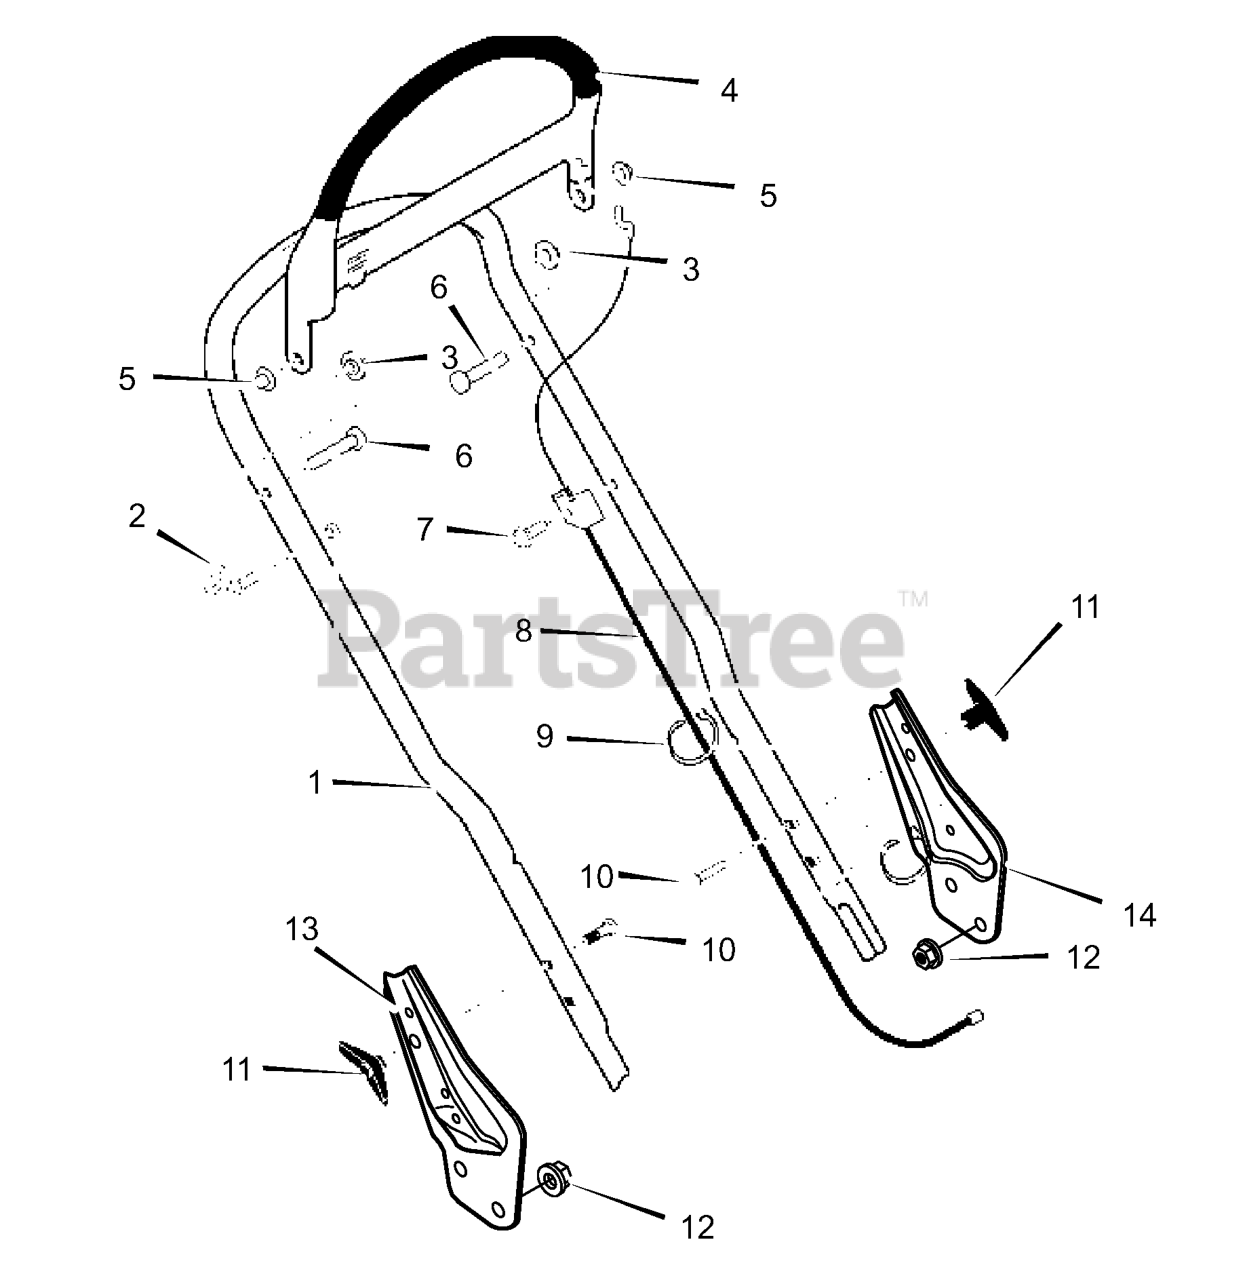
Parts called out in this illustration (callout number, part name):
1	Handle, Upper
2	Guide, Rope
4	Lever, Stop
5	Push-On Cap
6	Pin, Clevis
8	Cable, Stop
9	Strap, Tie
10	Bolt, Carriage
11	Wingnut
12	Nut
13	Bracket, Right Handle
14	Bracket, Left Handle
